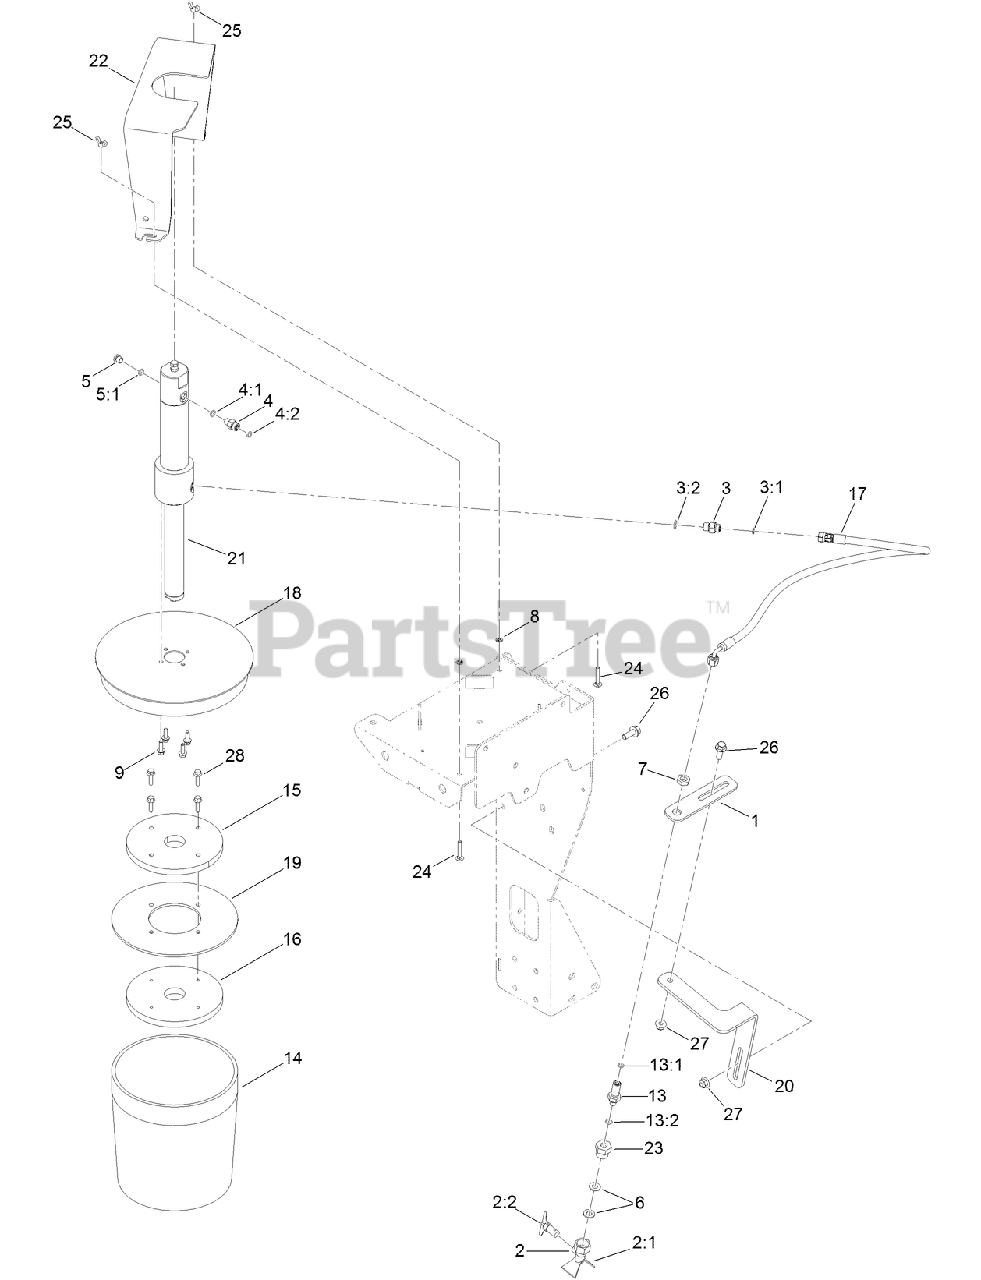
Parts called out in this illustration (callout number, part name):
1	PLATE-MOUNT, NOZZLE
2	SPRAY NOZZLE ASM
2:1	NOZZLE-SPRAY, AIRLESS
2:2	ORIFICE INSERT ASM
3	FITTING-STRAIGHT
3:1	O-RING
3:2	O-RING
4	FITTING-STRAIGHT
4:1	O-RING
4:2	O-RING
5	PLUG ASM
5:1	O-RING
6	WASHER-FLAT
7	NUT-LOCK
8	NUT-RETAINER
9	SCREW-HHF
13	FITTING-STRAIGHT
13:1	O-RING
13:2	O-RING
14	COMPOUND-THREAD
17	HOSE-HYD
18	COVER-APPLICATOR, LUBE
19	SEAL-RUBBER, FOLLOWER
20	PLATE-SUPPORT, NOZZLE
21	HYD GREASE PUMP ASM
22	TIEDOWN-COVER, GREASE
23	REDUCER-STRAIGHT, THREADED
24	SCREW-CARR
25	WINGNUT
26	SCREW-HHF
27	NUT-HF, NI
28	SCREW-HHF
